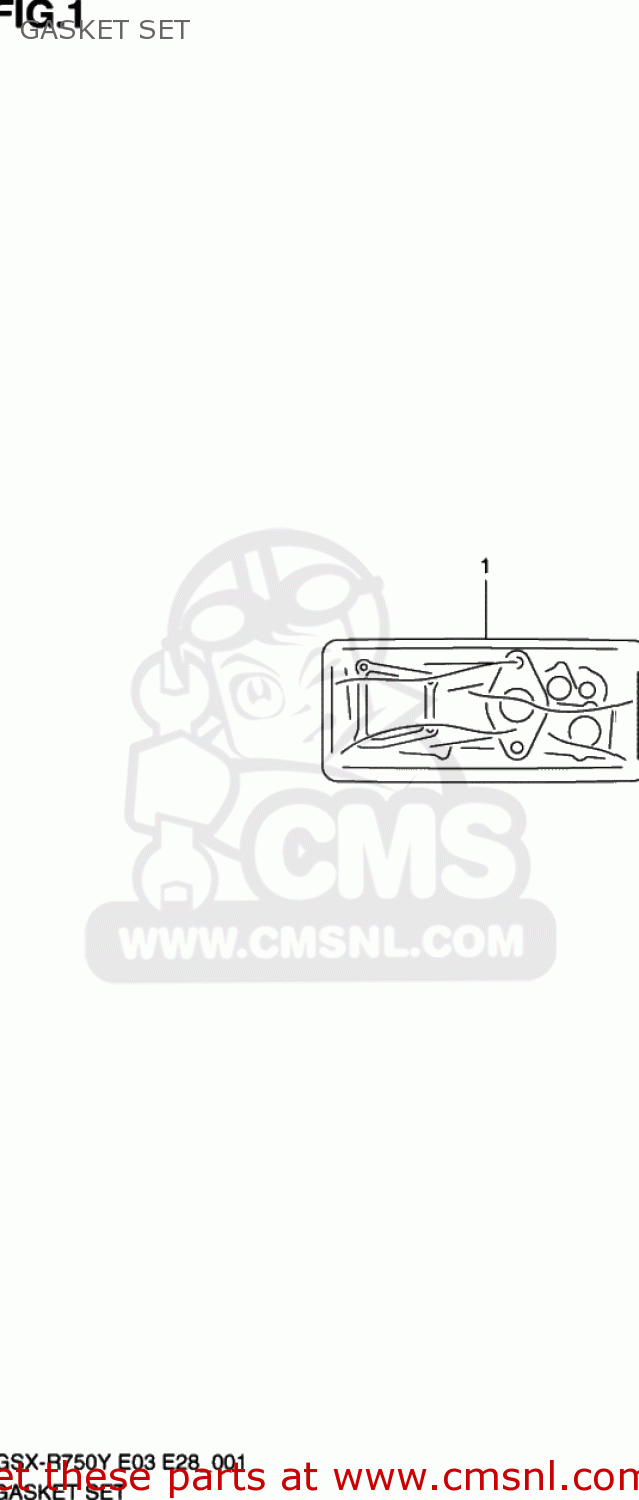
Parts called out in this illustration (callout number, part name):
1	GASKET SET (NAS)
2	GASKET,CYLINDER HEAD (NAS)
3	GASKET,CYL HEAD COVER NO.1 (NAS)
4	GASKET,CYL HEAD COVER NO.2
5	GASKET,2ND AIR PASSAGE (NAS)
6	WASHER(10.6X25.5X2.3)
7	GASKET,CL COVE (NAS)
8	GASKET,STARTER CLUTCH COVER
9	O RING(D:3.1,ID:32.7)
10	GASKET,START IDLE GEAR CAP (NAS)
11	GASKET,MAGNETO COVER (NAS)
12	GASKET,BREATHER COVER (NAS)
13	GASKET,OIL PAN (NAS)
14	GASKET,TENSIONER ADJUSTER (NAS)
15	GASKET,MUFFLER JOINT (NAS)
16	GASKET,EXHAUST PIPE
17	O RING(D:1.9,ID:7.8)
18	O RING,OIL PUMP
19	O RING(D:2.62,ID:20.3)
20	O RING(D:3.1,ID:63.9)
21	O RING,FUEL PUMP
